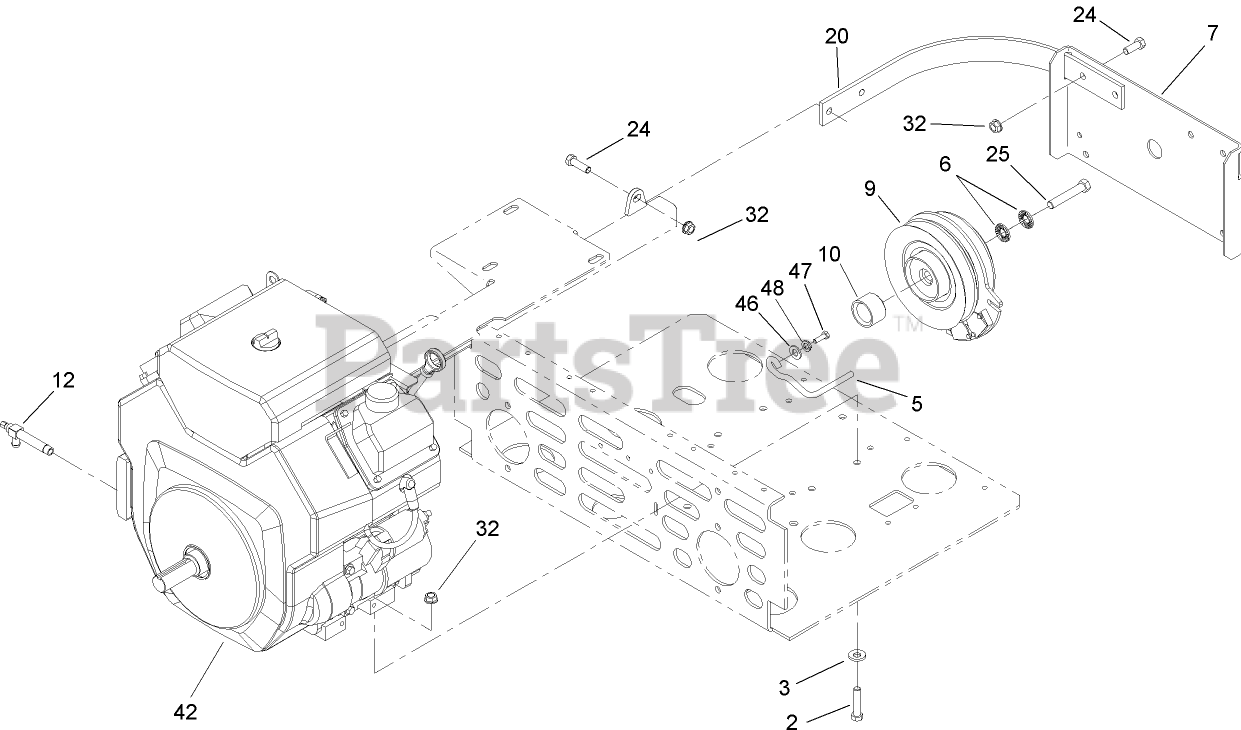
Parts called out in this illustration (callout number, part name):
2	SCREW-HH
3	WASHER-BELLEVILLE
5	ROD-BELT
6	WASHER-SPRING
7	GUARD-CLUTCH
9	CLUTCH
10	SPACER-CLUTCH
12	VALVE-OIL DRAIN, LONG
20	STRAP-GUARD
24	SCREW-HH
25	SCREW-HH
32	NUT-HHF, WHIZ
46	WASHER-FLAT
47	SCREW-HH
48	WASHER-BELLEVILLE
